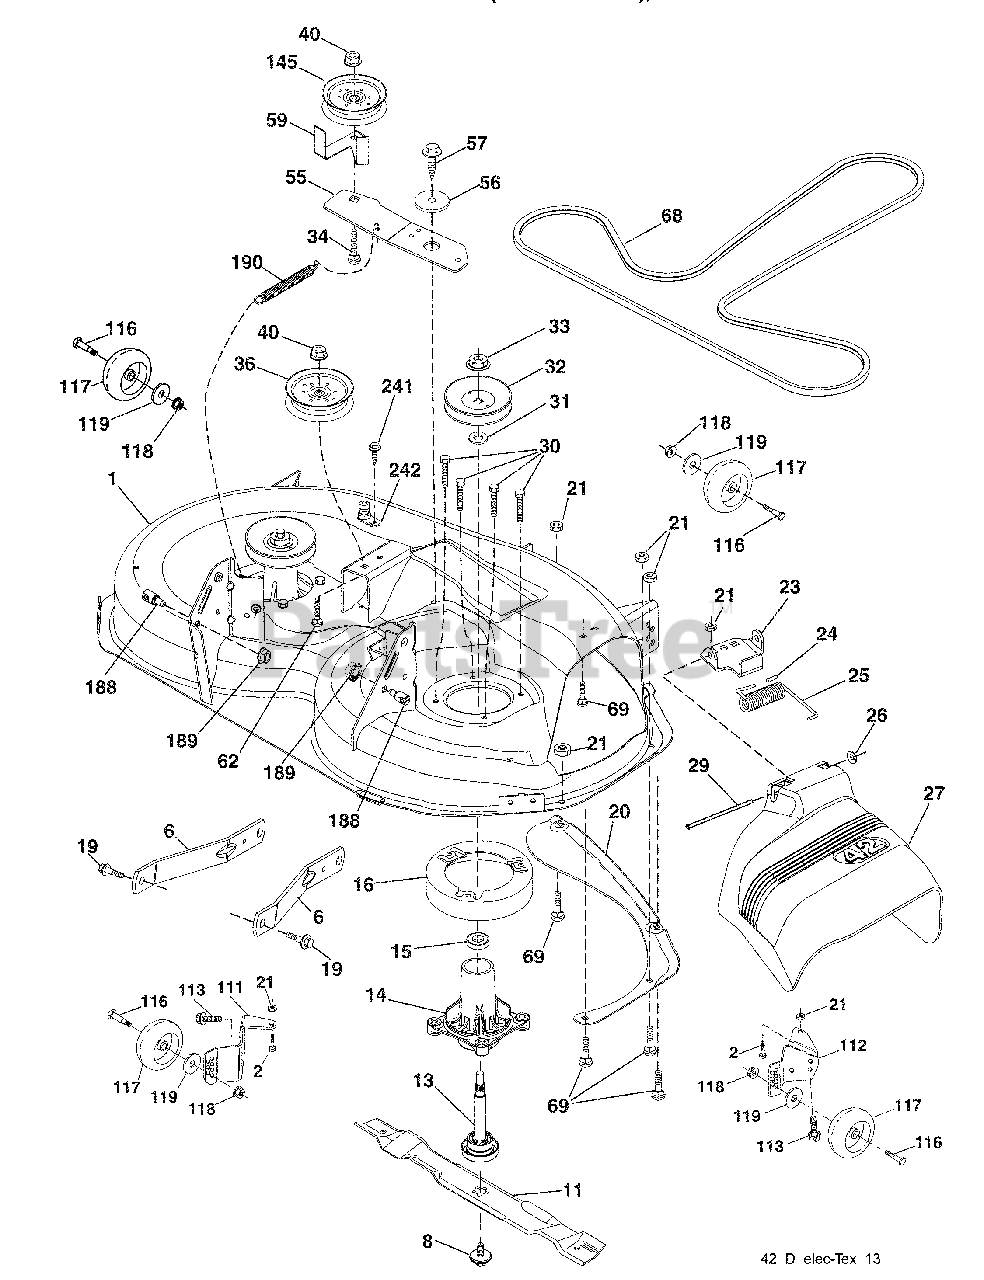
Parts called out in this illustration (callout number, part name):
1	Mower Housing
2	Bolt, Rdhd.5QNK 5/16-18 unc x 3/4
6	Arm Suspension
8	Bolt/Washer Asm 7/16-20 unf
11	Blade Mower
13	Shaft Assembly, Mandrel
14	Housing, Mandrel
15	Bearing, Ball, Mandrel
16	Stripper Mandrel
19	Bolt, Shoulder
20	Baffle Vortex
21	Nut
23	Bracket, Deflector
24	Cap, Sleeve
25	Spring, Torsion, Deflector
27	Shield, Deflector
29	Rod, Hinge
30	Screw Thdrol Rolling Wsh Hd
31	Washer, Spacer
32	Pulley, Mandrel
33	Nut, Toplock, Flanged
34	Bolt Carr Sh. 3/8-16 x1-1/2 Gr. 5
36	Pulley, Idler, Flat
40	Nut, Lock Flg. 3/8-16 unc
55	Arm, Idler
56	Spacer, Retainer
57	Screw Hexwsh Thd 3/8-16 x 1
59	Guard, Tuv Idler (94)
62	Bolt 3/8 - 16 unc x 2
69	Bolt
111	Bracket Wheel Gauge LH
112	Bracket Wheel Gauge RH
113	Screw 5/16-18
116	Bolt, Shoulder
117	Wheel, Gauge
118	Nut Centerlock 3/8 - 16 unc
119	Washer 3/8 x 7/8 x 14 Ga.
145	Pulley Idler
188	Stud Fastener
189	Nut Lock Hex Flange
190	Spring Mower Drive
241	Screw TT #10-32.5.3/8 Flange
242	Washout Port
